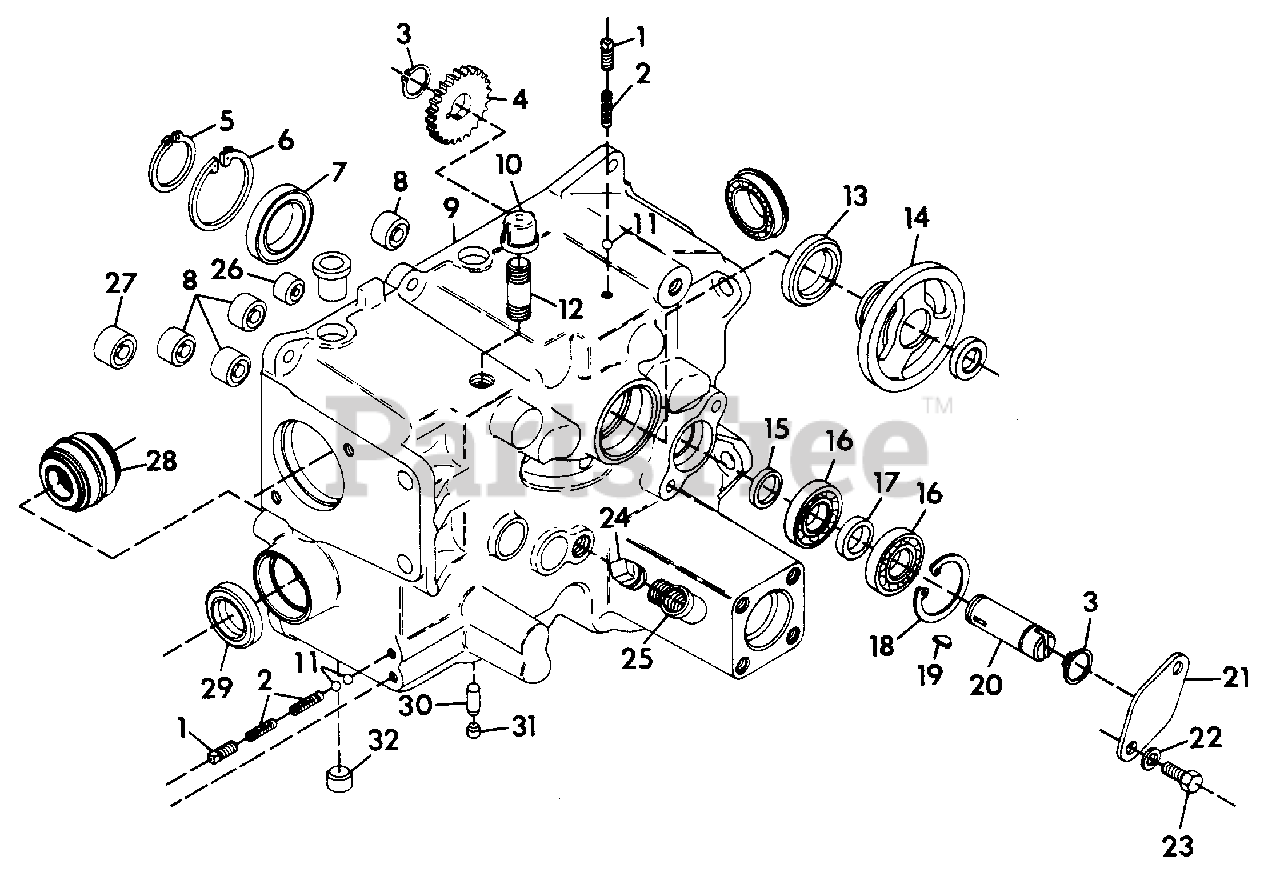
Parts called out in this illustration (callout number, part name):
1	PLUG, PIPE 1/8(4-SP)
1	PLUG, PIPE 1/8(8-SP)
2	SPRING, COMP. 1.50X.30X26 RATE(4-SP)
2	SPRING, COMP. 1.50X.30X26 RATE(8-SP)
3	RING, RETAINING .594 SHAFT
4	GEAR, HYDRAULIC PUMP
5	RING, RETAINING 1.969 SHAFT
6	RING, RETAINING 3.156 BORE
7	BEARING, BALL 1.968X3.149X.629
8	BEARING, NEEDLE .75X1.00X.75
9	ASSEMBLY, TRANSMISSION CASE(4-SP)
9	ASSEMBLY, TRANSMISSION CASE(8-SP)
10	CAP, PIPE 1/2 NPT
11	BALL, STEEL 5/16(4-SP)
11	BALL, STEEL 5/16(8-SP)
12	NIPPLE, PIPE 1/2X2.50
13	SEAL, OIL 2.250X3.005X.375
14	HUB, CLUTCH
15	SPACER, .620X.750X.276
16	BEARING, BALL .590X1.378X.433
17	SPACER, .620X.750X.364
18	RING, RETAINING 1.378 BORE
19	KEY, WOODRUFF .125X.375 HARD
20	SHAFT, HYDRAULIC PUMP
21	PLATE, COVER
22	WASHER, FLAT .406X.812X.065
23	BOLT, HEX 3/8-16X.75
24	PLUG, PIPE .5 SQ HD STEEL
25	EL, 1/2 90 STREET
26	BEARING, NEEDLE .625X.812X.750
27	BEARING, NEEDLE 1.000X1.250X.750
28	ASM., BEARING 1.000X1.980X1.243
29	SEAL, OIL 1.375X2.129X.312
30	PIN, INTERLOCK
31	PLUG, CUP 3/8
32	PLUG
